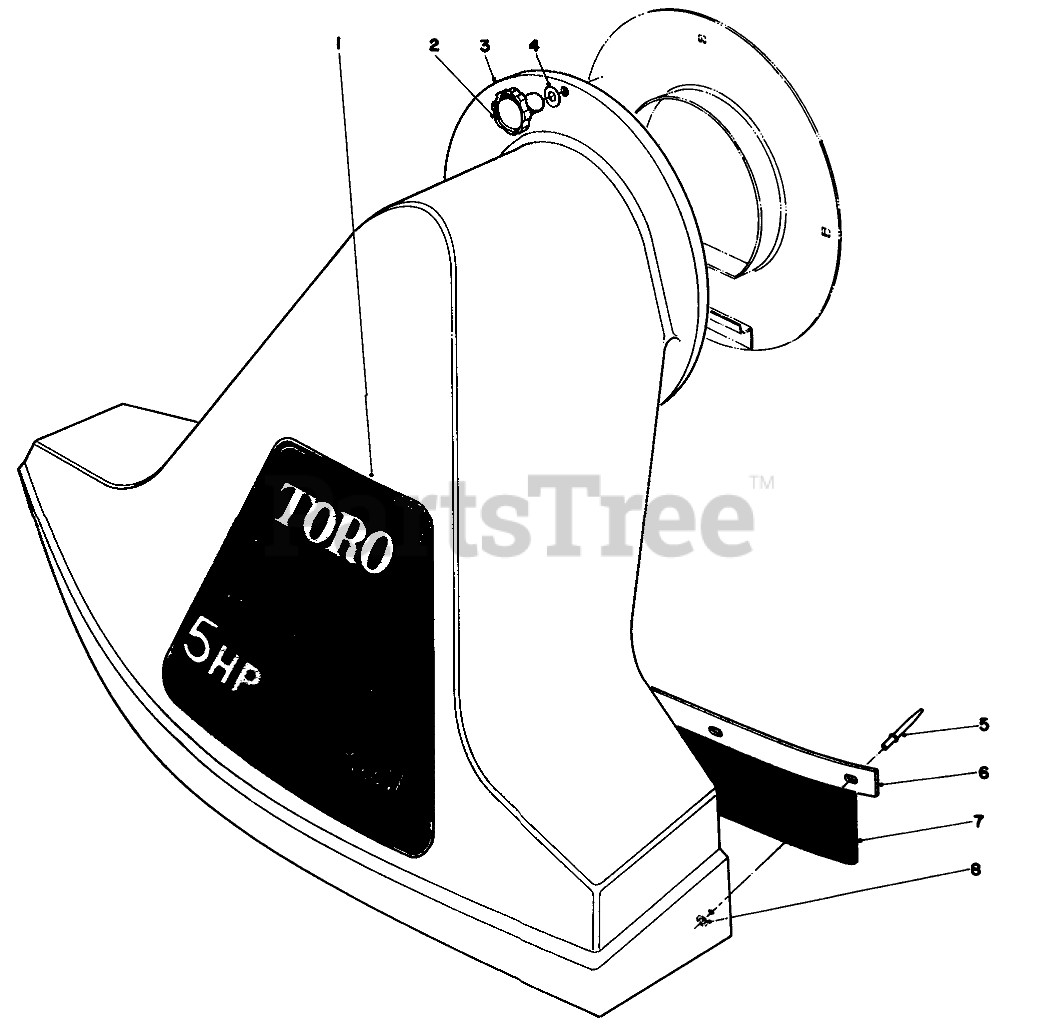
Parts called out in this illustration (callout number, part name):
1	DECAL - VACUUM HP
3	Snout Assembly (Incl. Ref. #5-8
4	Washer
5	POP RIVET 3/16X.375LG
6	Clamp-Flap
7	FLAP-RUBBER
8	WASHER-FLAT
